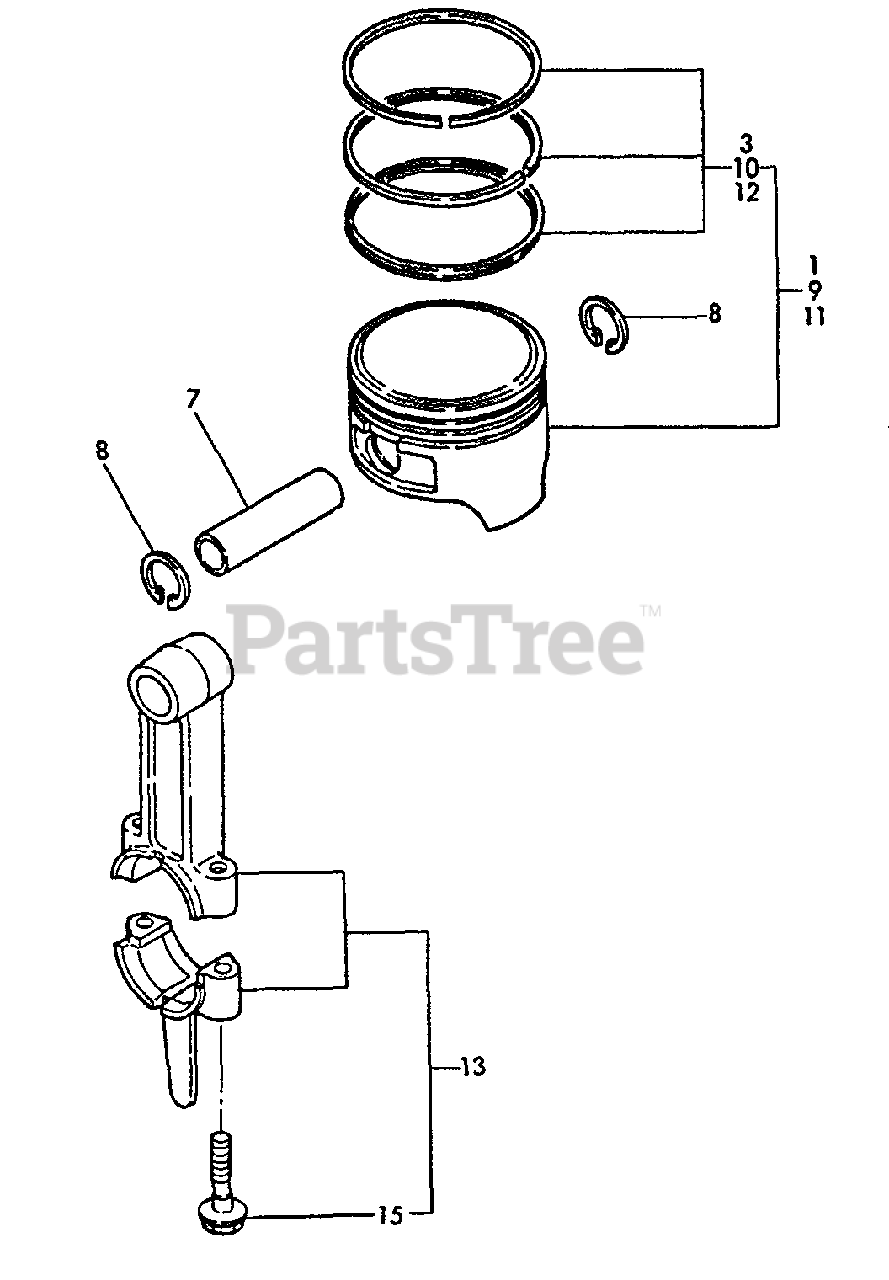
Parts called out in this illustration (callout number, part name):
1	PISTON ASSY
3	PISTON RING ASSY
7	PIN, PISTON
8	RING, RETAINING - 16
9	PISTON ASSY O.S.=0.25
10	RING ASSY O.S.=0.25
11	PISTON ASSY O.S.=0.5
12	RING ASSY O.S.=0.5
13	CONNECTING ROD ASSY
15	BOLT, ROD
